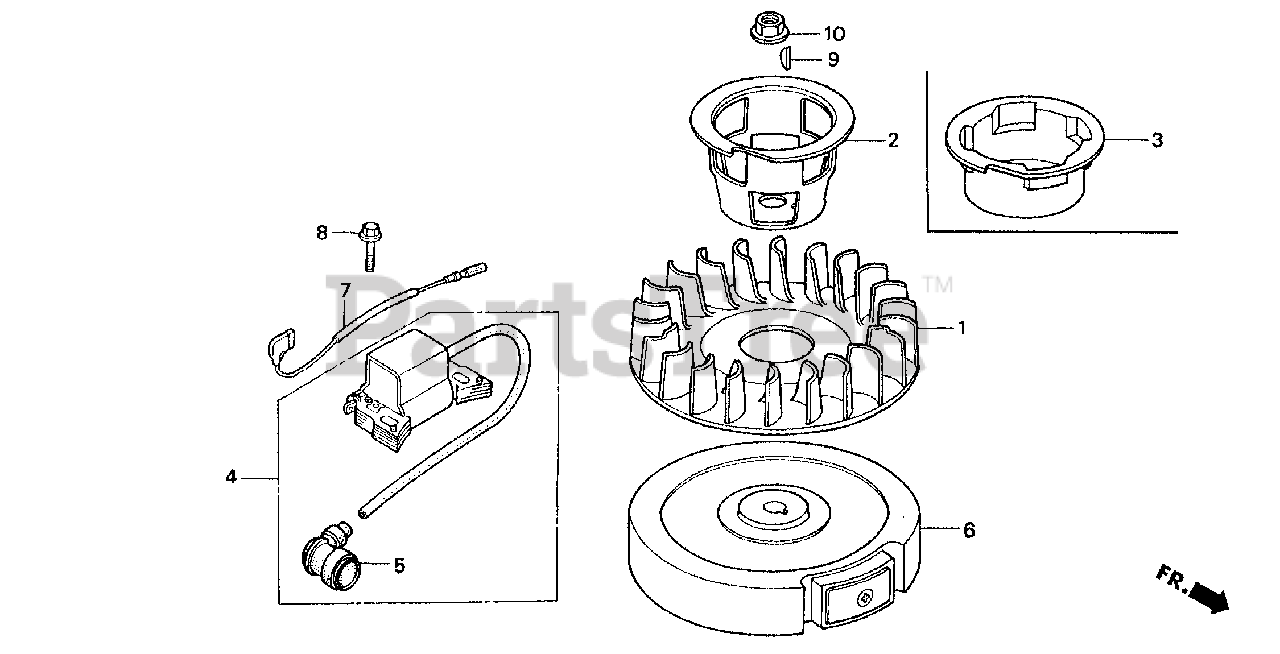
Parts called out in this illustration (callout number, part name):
1	FAN, COOLING
2	PULLEY, STARTER
4	COIL ASSY., IGNITION
5	CAP ASSY., NOISE SUPPRESSOR
6	FLYWHEEL
7	WIRE, STOP SWITCH
8	BOLT, FLANGE (6X25)
9	KEY, WOODRUFF (3MM)
10	NUT, FLANGE (12MM)
